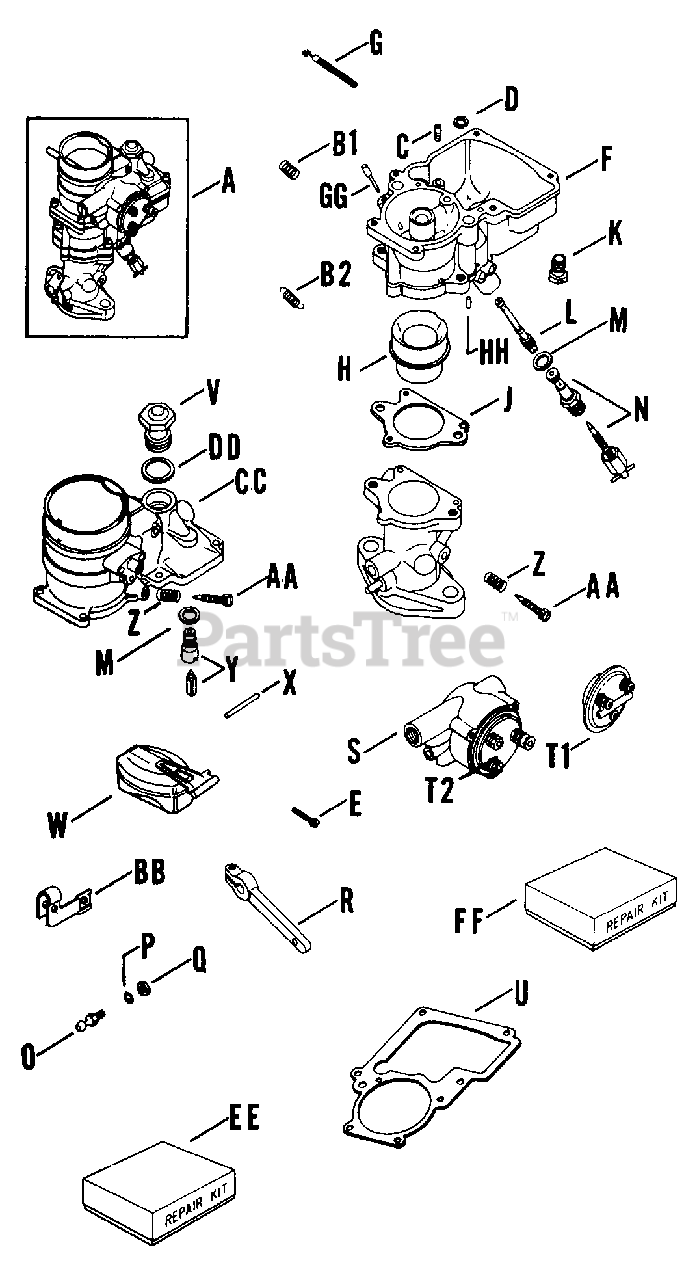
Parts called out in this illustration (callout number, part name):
A	CARBURETOR ASSY - DISCONTINUED
D	WASHER - DISCONTINUED
J	Gasket, body to bowl
K	PLUG, PIPE DISCONTINUED
L	JET - DISCONTINUED
N	JET - DISCONTINUED
O	JOINT - DISCONTINUED
U	GASKET - DISCONTINUED
W	FLOAT - DISCONTINUED
Y	KIT - USE 272408
Z	KIT - USE 277896
EE	KIT, CARBURETOR REPAIR - DISCONTINUED
